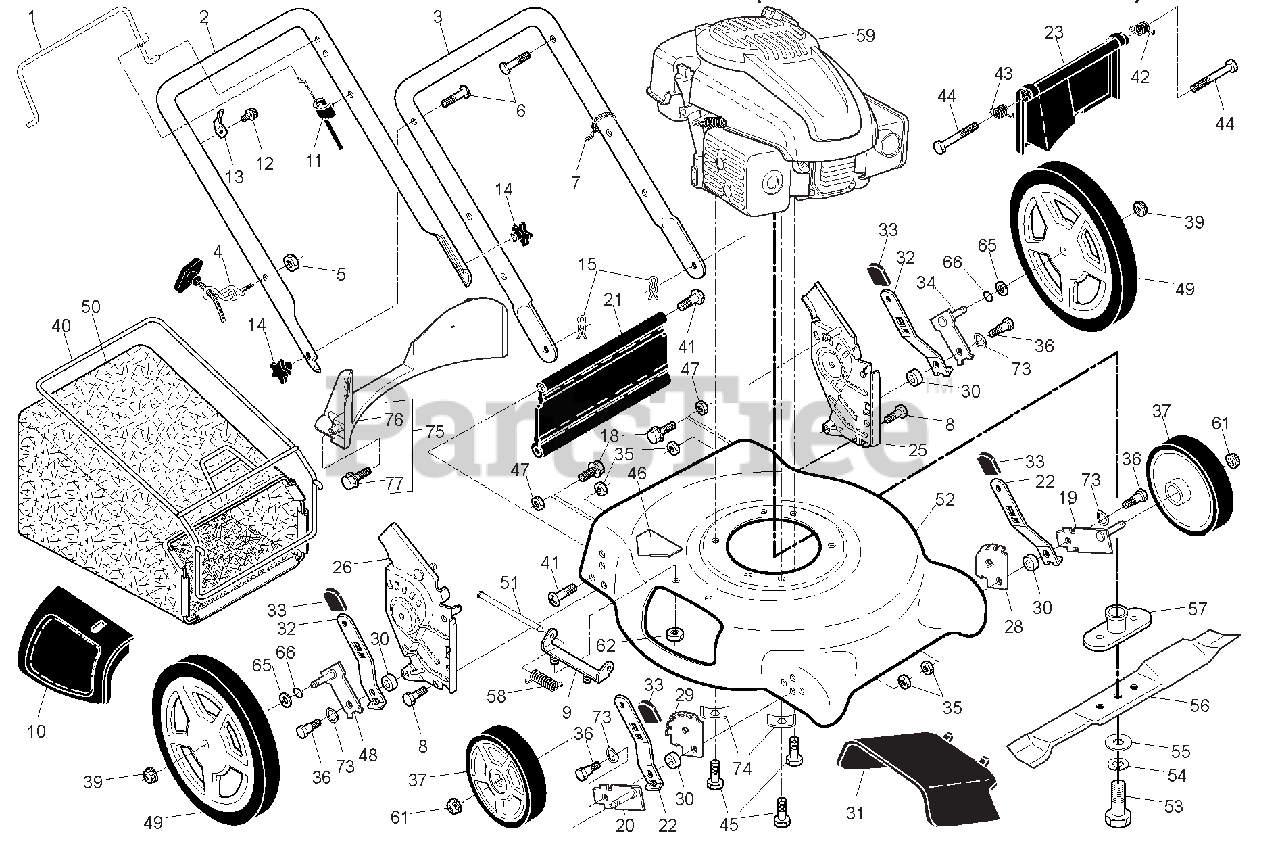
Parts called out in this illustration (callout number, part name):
1	Control Bar
2	Upper Handle
3	Lower Handle
4	Rope Guide
5	Nut, Hex
6	Handle Bolt
7	Wire Tie
8	Bolt, Hex Head 5/16-18 x 3/4
9	Hinge Bracket
10	Mulcher Door
11	Engine Zone Control Cable
12	Hex Washer Head Screw
13	UP-STOP BRACKET
14	Handle Knob
15	Hairpin Cotter
18	SCREW.HEX.WASHEAD.1/4-20 X 3/8
19	Axle Arm Assembly, Front, LH
20	Axle Arm Assembly, Front, RH
21	Kit, Rear Skirt
22	Selector Spring, Front
23	Rear Door Assembly
25	Handle Bracket Assembly, LH
26	Handle Bracket Assembly, RH
28	Wheel Adjusting Bracket, LH
29	Wheel Adjusting Bracket, RH
31	Discharge Deflector
32	Selector Spring, Rear
33	Selector Knob
34	Axle Arm Assembly, Rear, LH
35	Locknut, Hex 5/16-18
36	Shoulder Bolt
37	Wheel & Tire Assembly, Front
39	Flanged Locknut, Hex
40	Frame, Grassbag
41	Hinge Screw
42	Spring, Rear Door, LH
43	Spring, Rear Door, RH
44	Bolt, Rear Door
45	Screw, Hex Head, Threaded, Rol
46	Danger Decal
47	Nut, Hex
48	Axle Arm Assembly, Rear, RH
49	Wheel & Tire Assembly, Rear
50	Grassbag
51	Hinge Rod
52	Kit, Lawn Mower Housing (Includes Key Number 46)
53	Screw, Hex Head, Grade 8 3/8-2
54	Helical Lockwasher
55	Hardened Washer
56	21" Blade
57	BLADE ADAPTER
58	Hinge Spring
61	Nut, Hex
62	Locknut, Hex 1/4-20
65	Washer, Flat
73	Washer, Curved, Cylindrical
74	Washer, Special, Engine
75	Kit, Rear Baffle (Includes 3 S
76	Baffle, Rear
77	Screw, Rear Baffle
